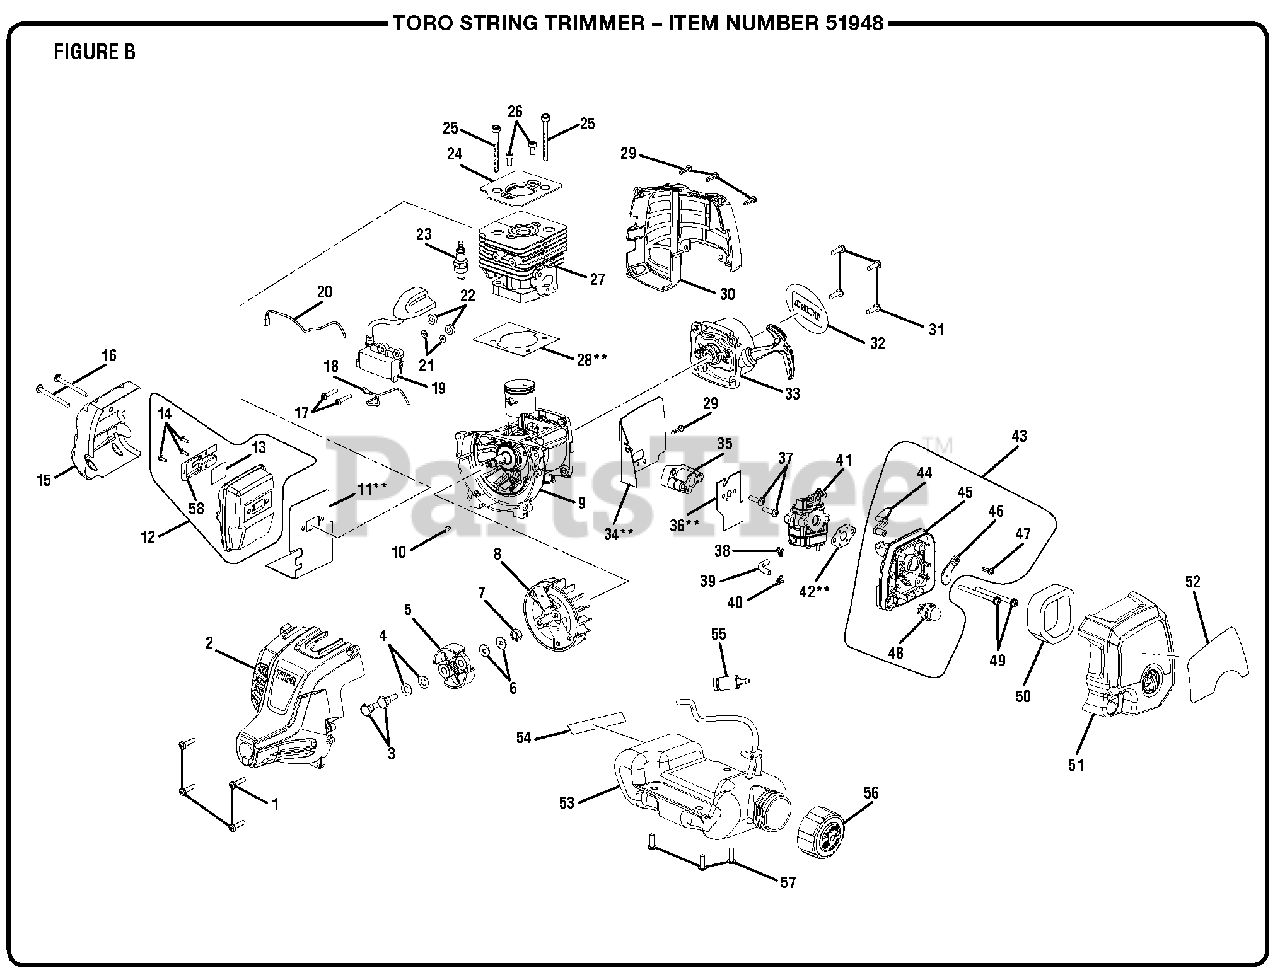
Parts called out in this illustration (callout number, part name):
1	Screw (M5 x 20 mm, T20 Torx Pan Hd.)
2	Front Housing Assembly
3	Clutch Shoulder Bolt (M6 x 22.5 mm, Hex Hd.)
4	Curved Washer
5	Clutch Assembly
6	Washer (ID6 x OD15 x 1.2t)
7	Flywheel Nut
9	Crankcase Assembly
10	Woodruff Key (10 mm x 3 mm)
11	Muffler Gasket
12	Muffler Assembly
13	Screen
14	Screw (6-20 x 1/4 in., T20 Torx Pan Hd. S.T.)
15	Heat Shield
16	Screw (M5 x 50 mm, T25 Torx Soc. Hd.)
17	Screw w/Washer (M4 x 22 mm, T25 Torx Soc. Hd.)
18	Lead Wire (Red)
19	Coil Boot Assembly
20	Lead Wire (Black)
21	Washer (ID4.2 x OD10 x1t)
22	Spacer (Phenolic)
23	Spark Plug (Champion RCJ4)
24	Cylinder Plate
25	Screw (M5 x 22 mm, T25 Torx Soc. Hd.)
26	Screw w/Washer (M5 x 10 mm, T25 Torx Pan. Hd.)
28	Gasket
29	Screw (M4 x 18 mm, T20 Torx Pan Hd. S.T.)
30	Rear Engine Housing
31	Screw w/Washer (M5 x 16 mm, T25 Torx Soc. Hd.)
32	Logo Label (Rear)
33	Starter Recoil & Starter Cup Assembly
34	Insulator Gasket
35	Heat Dam Insulator
36	Gasket
37	Screw w/Washer (M5 x 31 mm, T20 Torx Pan Hd.)
38	Hose Clip
39	Fuel Line (45 mm)
40	Hose Clip
41	Carburetor Assembly
42	Carburetor Gasket
43	Airbox Base Assembly
44	Choke Lever
45	Airbox Base
46	Choke Plate
47	Screw (M4 x 12 mm, T20 Torx Pan Hd. S.T.)
48	Primer Assembly
49	Screw (M5 x 60 mm, T25 Torx Cap Soc. Hd.)
50	Air Filter
51	Airbox Cover Assembly w/Label
52	Starting Instructions Label
53	Fuel Tank & Cap Assembly
54	Combustion Warning Label
55	Fuel Filter
56	Fuel Cap Assembly
57	Screw (M5 x 16 mm, T25 Torx Soc. Hd.)
58	Outlet Tube
